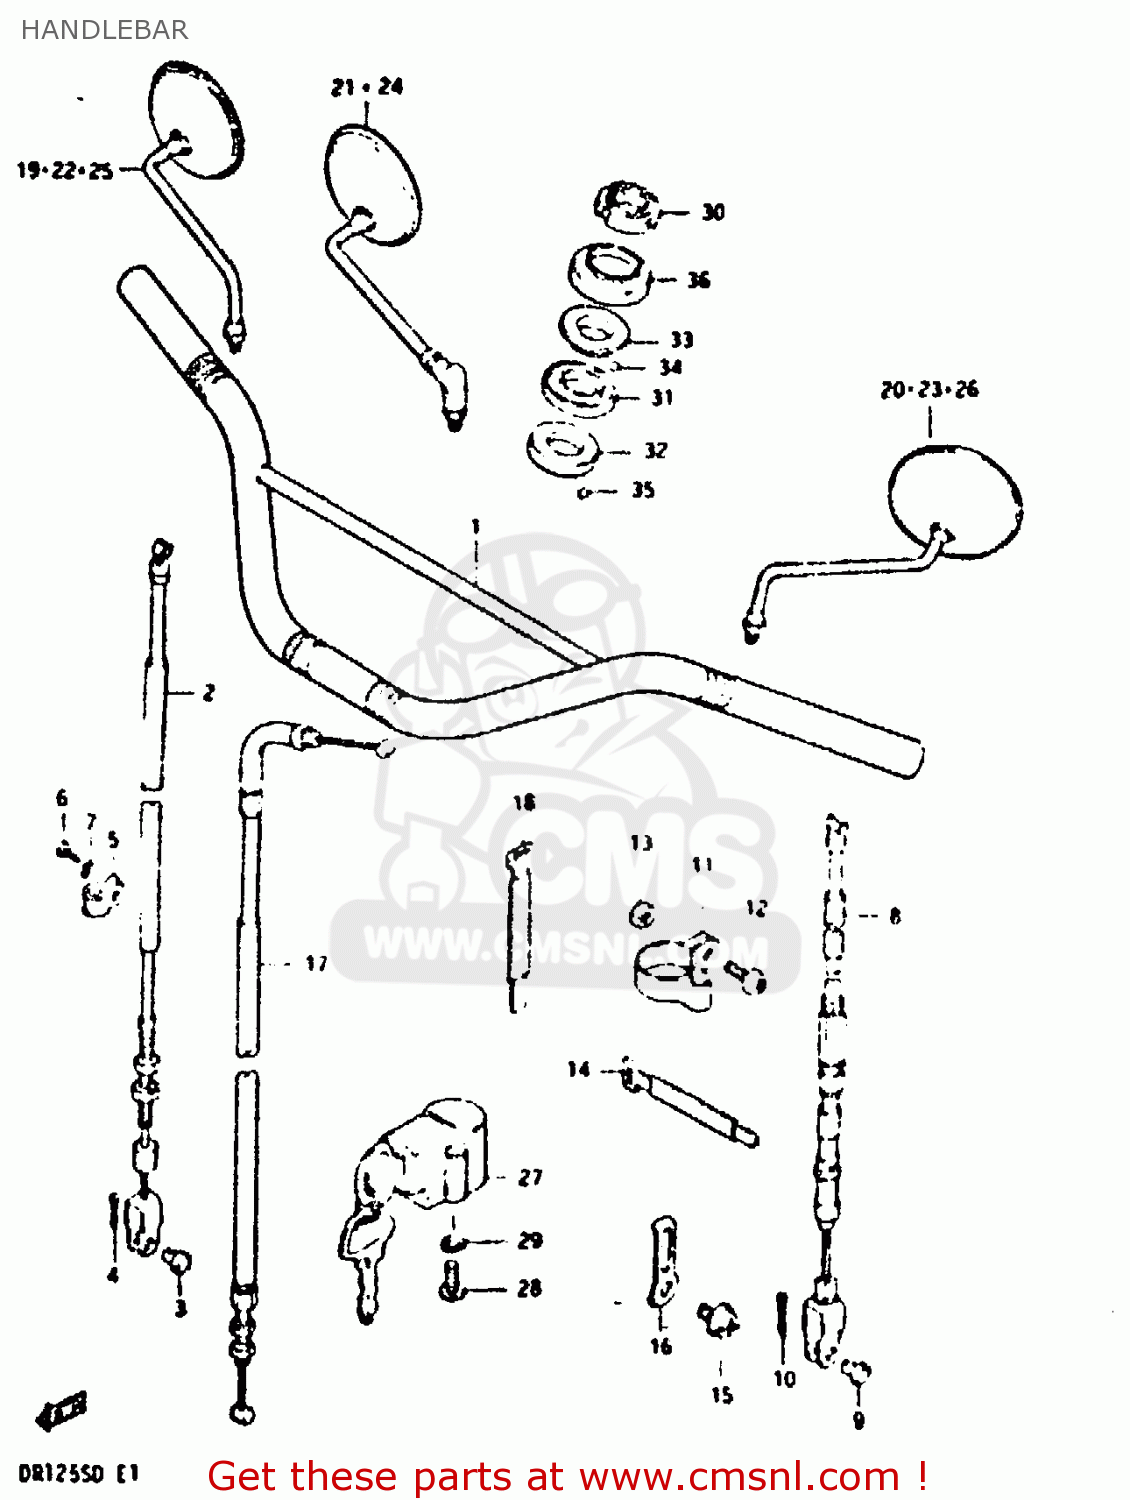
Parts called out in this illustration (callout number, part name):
1	HANDLE BAR
2	CABLE,FRONT BRAKE
3	PIN(L:17.5)
4	PIN
5	CLAMP,FR BRAKE CABLE
6	SCREW 6X12
7	LOCK WASHER
8	CABLE ASSY,CLUTCH
9	PIN(L:15)
10	PIN
11	CLAMP, NO. 2
12	SCREW
13	NUT
14	CLAMP
15	SCREW
16	CLAMP,CABLE
17	CABLE ASSY,THROTTLE
18	CLAMP
21	MIRROR ASSY,RH
27	LOCK ASSY,STEERING
28	SCREW
29	LOCK WASHER
30	NUT,STEERING STEM(25X44X10)
31	RACE,STEERING INNER UPR
32	LACE,STEERING INNER LWR
33	RACE,STEERING OUTER UPR
34	BALL
35	BALL
36	DUST SEAL,STEERING UPR
